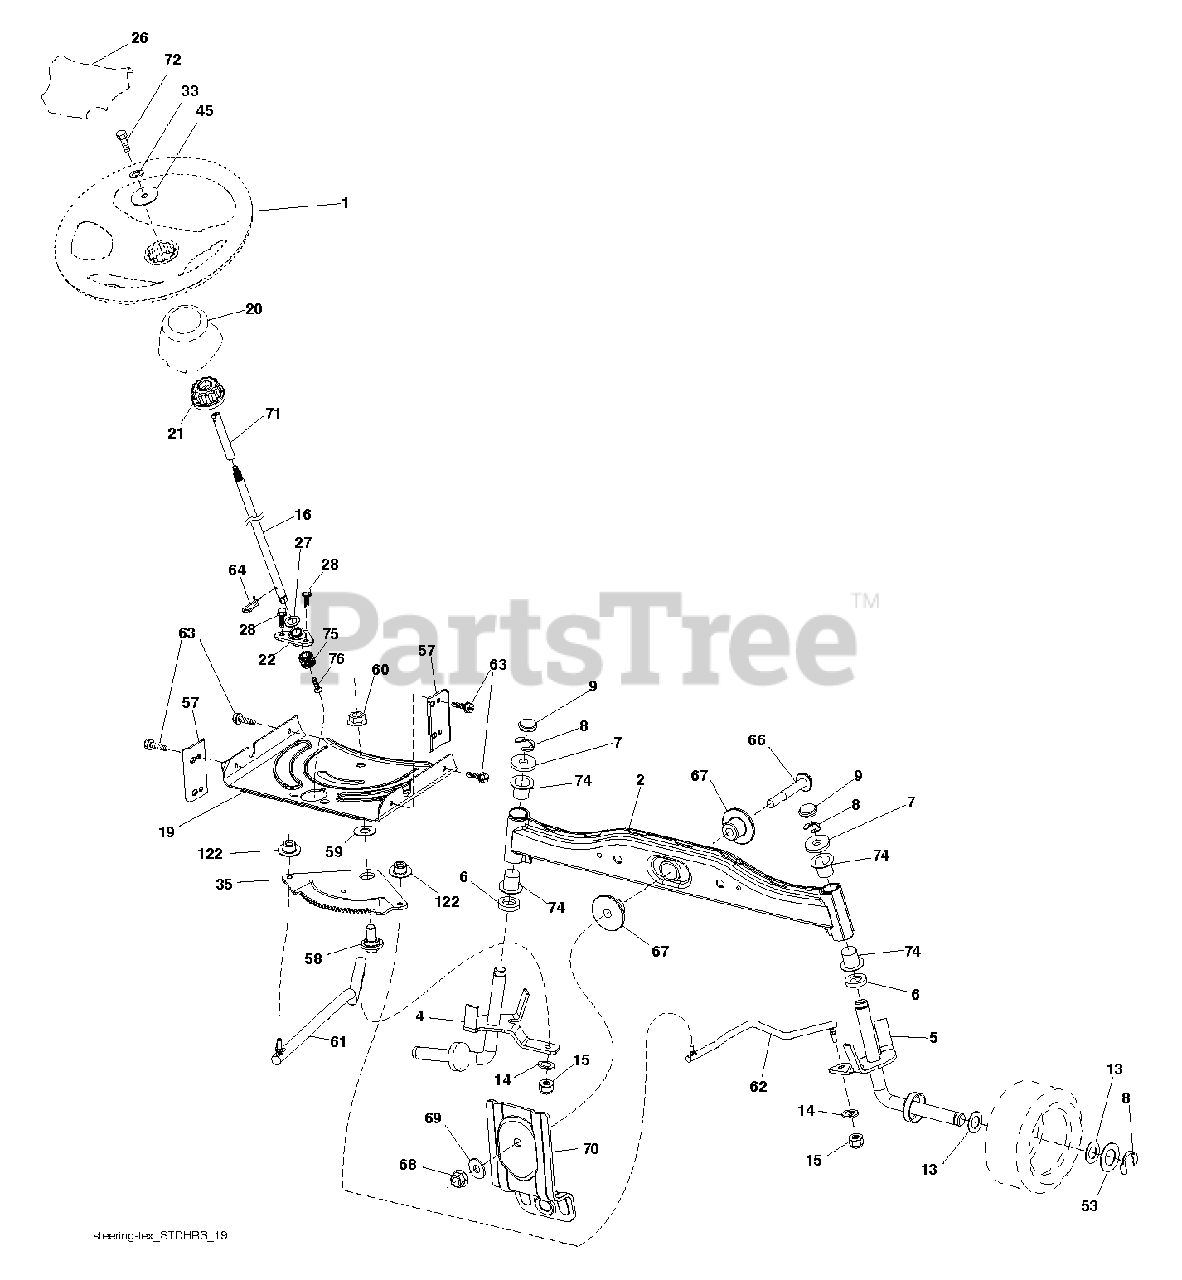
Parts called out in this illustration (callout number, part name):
1	WHEEL.STEERING.HARD.RIM.BLAC
2	AXLE HALF ASM-WELDED
4	SPINDLE.WELDED.LH.15"TEX
5	SPINDLE.WELDED.RH.15"T
8	RING CLIP
9	CAP.SPINDLE.BLACK
14	WASHER, LOCK 3/8
15	NUT CROWNLOCK 3/8-24
19	PLATE.STEER.DDL.NLT/NG
20	BOOT STEERING BLACK
21	ADAPTER, WHEEL STNG..
26	INSERT, WHEEL STEERING
27	WASHER LT
28	SCREW, 3/8-16X3/4
33	LOCKWASHER
35	GEAR.SECTOR.PLATE.DDL.
45	WASHER.11/32
53	WASHER.HARDENED
57	BRACKET.UPSTOP.TEX
58	BOLT.SHOULDER.SECTOR.P
59	WASHER.THURST.SECTOR.S
60	NUT FLANGE LOCK 5/8-11
61	DRAGLINK.LH.BALLSTUD.D
62	DRAGLINK.RH.BALLSTUD.D
63	SCREW
64	RETAINER.CLIP.SPRING.S
66	BOLT HEX FGHD 7/16-14 X 3 SERR
67	BUSHING.PM.FRONT AXLE
68	NUT.LOCK.FLANGE.7/16
69	WASHER.1.5X.505X.118
70	Deck Suspension Bracket, Front RR
71	SHAFT.EXTEN.STRG.SPLINE
72	BOLT 5/16-18 X 4 W/PATCH
74	Steering Column Bearing
76	Screw Head Socket Lrvb
122	CAP.GEAR.SECTOR.TEX
